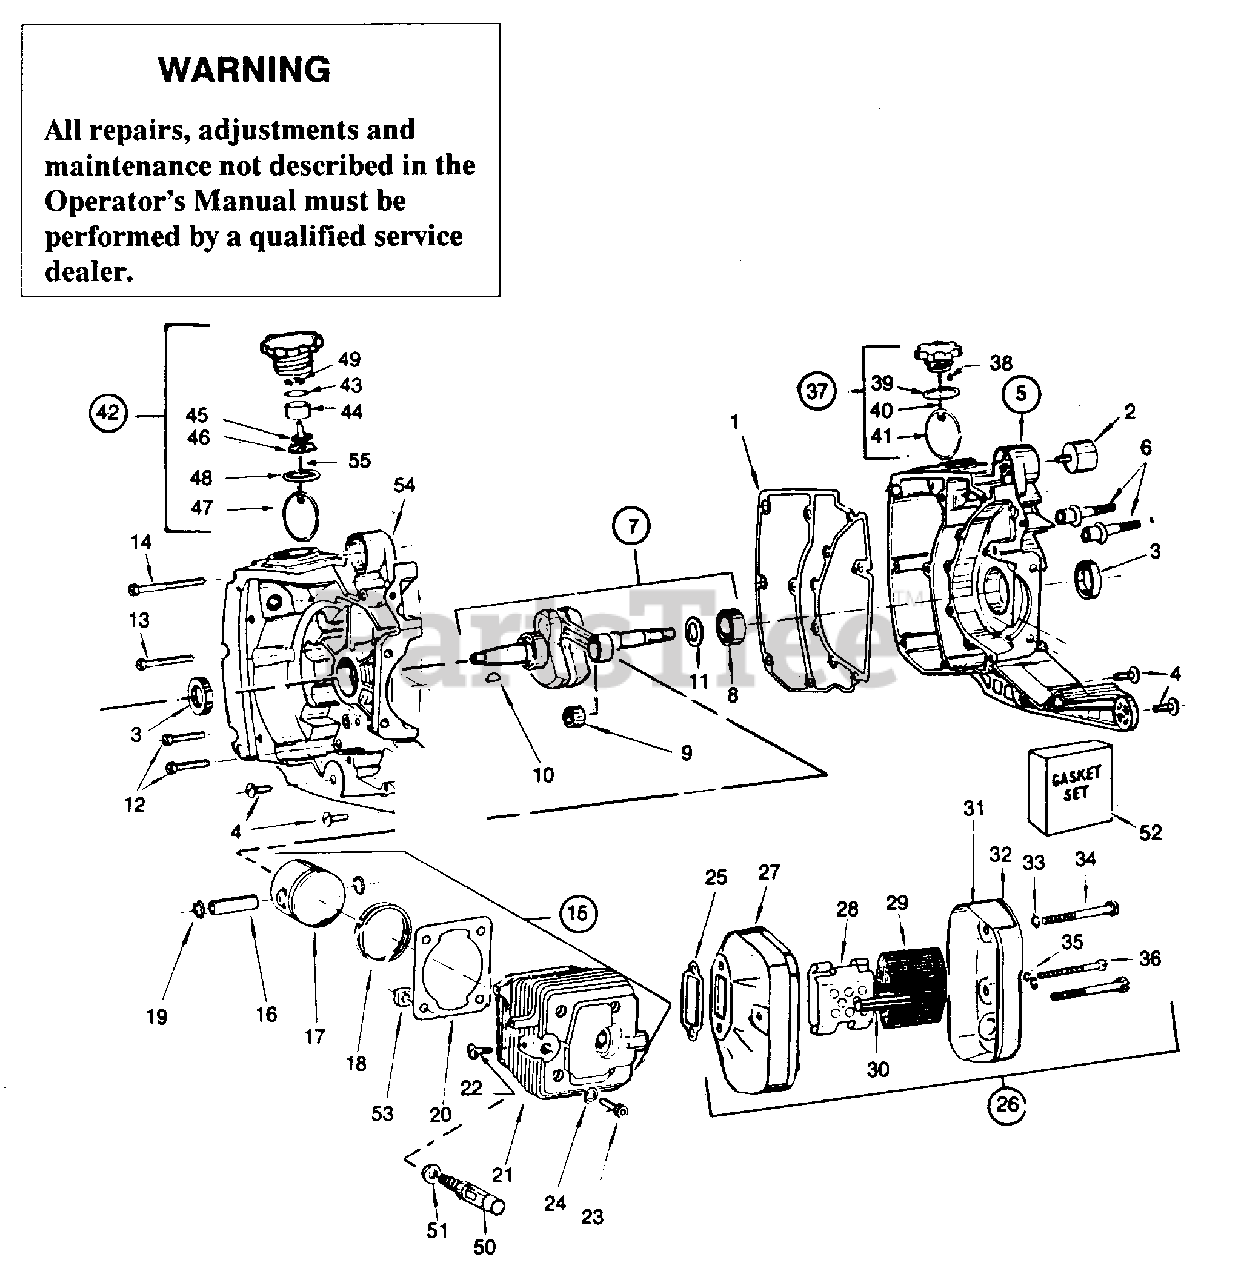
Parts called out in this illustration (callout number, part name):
1	C'Case Gasket
2	Shock Absorber
4	Screw - Shock Mount
5	Crankcase & Stud Assy
6	Bar Mounting Studs
7	C'Shaft Assy
8	Main Bearing
10	Flywheel Key (Machined)
11	Thrust Washer
12	Screw 10 - 24 X 1 1/4
13	Screw 10 - 24 X 2 1/4
14	Screw 10 - 24 X 2 1/2
15	Cyl./Piston/Ring Set
16	Wrist Pin
18	Piston / Ring Set
19	Retainer - Wrist Pin
20	Cylinder Base Gasket
21	Cylinder
22	Plate Screw
23	Screw 1/4 - 28 X 1
25	Muffler Gasket
26	Muffler Assy
27	Muffler Body
28	Muffler Channel (2 Req'd)
29	Muffler Screen
31	Muffler Cover
32	Heat Shield Assy
33	Lockwasher
34	Screw - Muffler
35	Lockwasher
37	Oil Cap Assy (Grey)
39	O-Ring Oil Cap
40	Bead Chain (Oil Cap)
41	Retainer - Oil Cap
42	Gas Cap Assy (Grey)
45	Umbrella Valve
46	Cover Gas Cap
47	Retainer - Gas Cap
48	Gas Cap O-Ring
50	Decompression Valve (Grey)
52	Gasket Set
54	C'Case Half M/S/ (Gold)
55	Bead Chain Gas Cap
